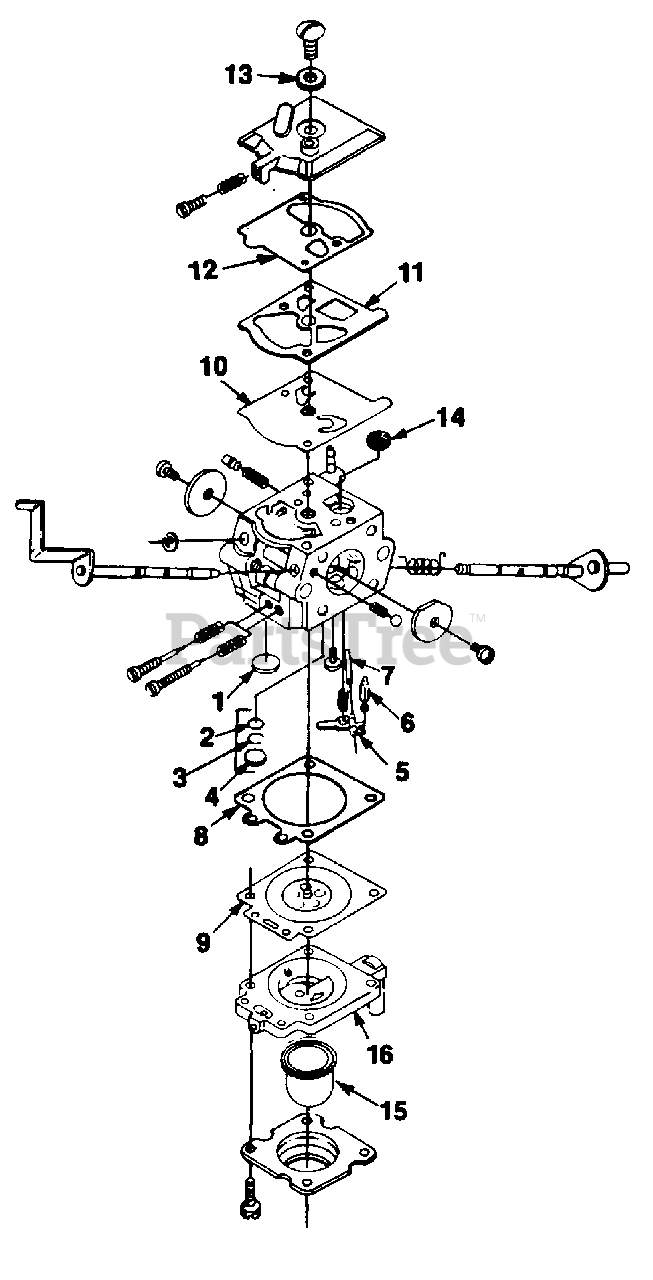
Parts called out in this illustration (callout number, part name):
1	Repair Kit
2	Repair Kit
3	Repair Kit
4	Repair Kit
5	Repair Kit
6	Repair Kit
7	Repair Kit
8	Repair Kit
9	Repair Kit
10	Repair Kit
11	Repair Kit
12	Repair Kit
13	Repair Kit
14	Repair Kit
15	Primer Bulb
16	Primer Base
